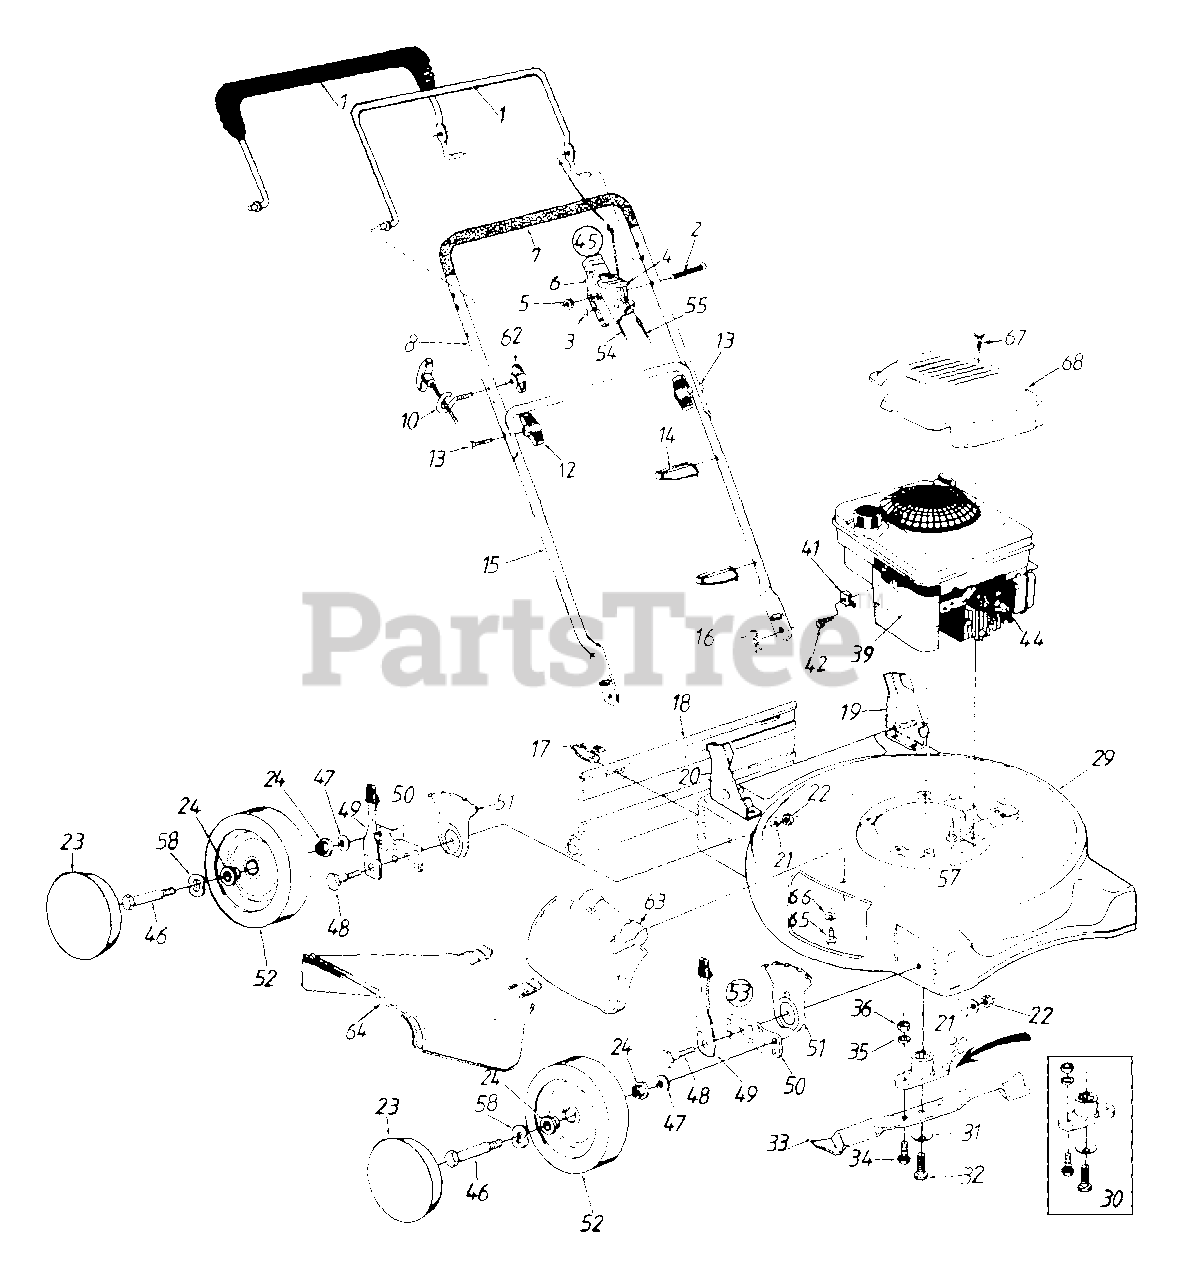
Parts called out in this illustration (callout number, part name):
1	Control Handle Ass'y.
2	Oval C-Sunk Scr.
3	Spr. Wash. .66" I.D.
4	Throttle Lever
5	Hex L-Nut 1/4-20 Thd.
6	Throttle Body
8	Upper Handle
10	Rope Guide
12	Hand Knob
13	Curved Hd. Bolt 5/16-18 x 2" Lg.
14	Cable Tie
16	Hairpin Cotter
17	Hinge Clip
18	Rear Flap
22	Hex Nut 3/8-16 Thd.
23	Hub Cap
24	Bearing
29	20" Deck Ass'y.
30	Blade Adapter Kit
31	Bell-Wash. .46" I.D.
32	Hex Bolt 7/16-20 x 1.5" Lg.
33	20" Mulching Blade
34	Hex Bolt 3/8-24 x 1" Lg.
35	L-Wash. 3/8" I.D.
36	Hex Nut 3/8-24 Thd.
39	Engine
41	Cable Clamp
42	Hex Self-Tap Scr. #10-32 x .62"
44	Spark Plug Boot
45	Throttle Box Comp.
46	Axle Bolt
47	Bell-Wash. .400" I.D. x .88"
48	Shld. Bolt .50" Dia. x .357"
49	Spring Lever Ass'y. w/Knob
51	Height Adj. Plate
52	Wheel Ass'y. Comp.
53	Height Adj. Ass'y. Comp. - R.F. & L.R.
53	Height Adj. Ass'y. Comp. - L F. & R.R.
54	Throttle Cable - 51"
55	Control Cable - 39"
57	Hex L-Wash Hd. Scr. 3/8-16 x 1.0" Lg.
58	Wave Washer .51" I.D.
62	Handle Knob 1/4-20 Thd.
63	Mulching Plug
64	Chute Deflector
65	Bell-Wash. 1/4" I.D.
66	Hex Wash. Hd. TT-Tap Scr. 1/4-20 x .5" Lg.
67	Hi-Lo Scr. #10 x 1.25" Lg.
68	Engine Shroud
